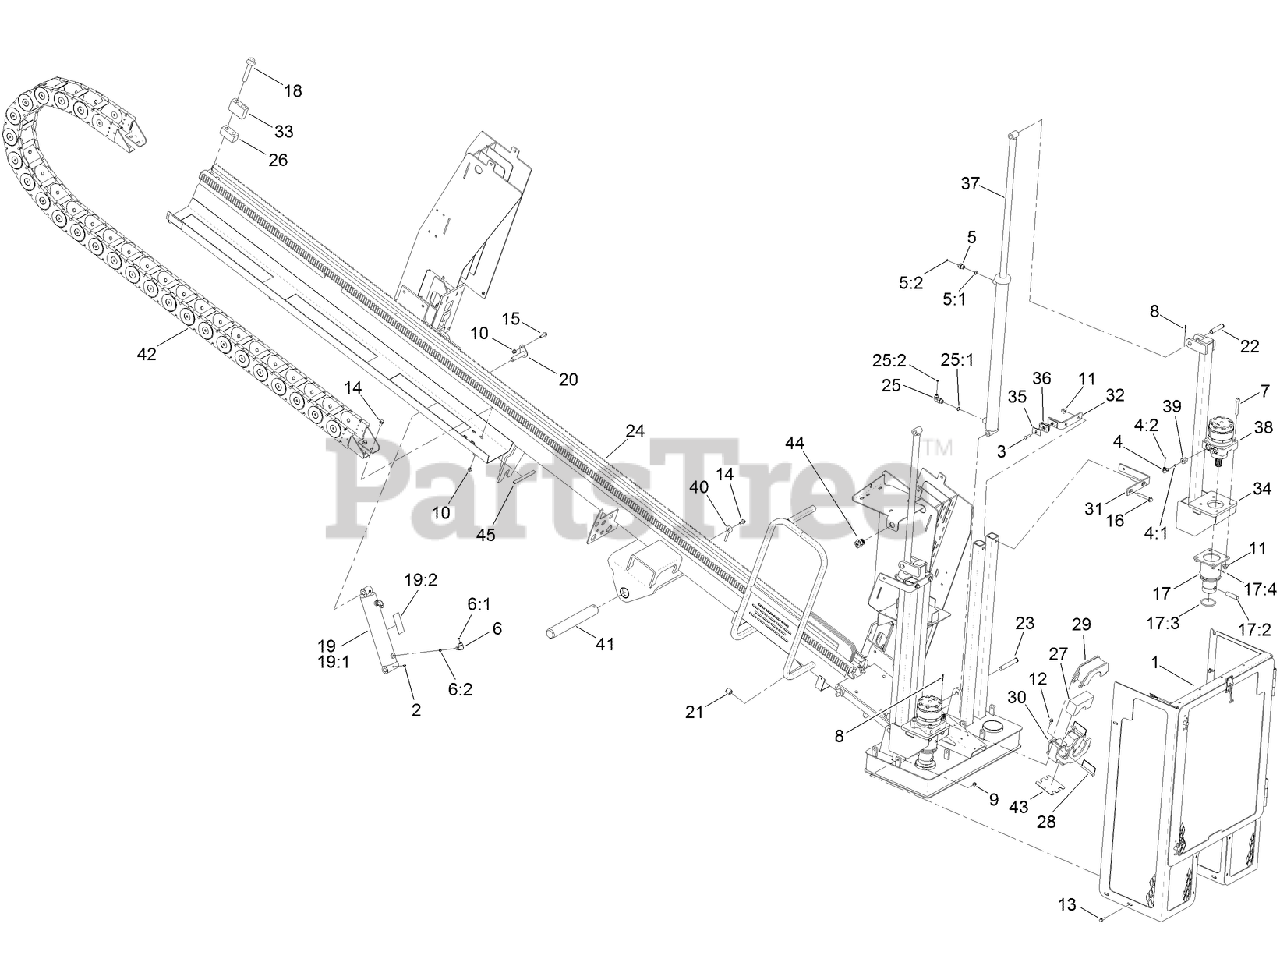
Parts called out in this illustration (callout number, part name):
1	STAKEDOWN CAGE ASM
2	FITTING-GREASE
3	SCREW-HH
4	FITTING-90 DEG
4:1	O-RING
4:2	O-RING
5	FITTING-STR
5:1	O-RING
5:2	O-RING
6	FITTING-ELBOW, 90 DEG
6:1	O-RING
6:2	O-RING
7	SCREW-HSH
8	PIN-COTTER
9	NUT-LOCK, HHF
10	NUT-LOCK, NI
11	NUT-LOCK, HHF
12	SCREW-HHF
13	SCREW-HHF
14	SCREW-HHF
15	SCREW-HHF
16	SCREW-HHF
17	STAKEDOWN COUPLER ASM
17:2	PIN-COUPLING, STAKE
17:3	O-RING
17:4	FITTING-GREASE
18	SCREW-HHF
19	LIFT CYLINDER ASM
19:1	CYLINDER-HYDRAULIC
19:2	DECAL-CAUTION, CYLINDER LOCK
20	PIN-FLAG
21	BUSHING-SPRING
22	PIN-CLEVIS
23	PIN-CLEVIS
24	THRUST FRAME ASM
25	FITTING-ELBOW 90
25:1	O-RING
25:2	O-RING
26	BLOCK-TAPPED
27	GUIDE-ROD, BUSHING
28	PIN-SELF LOCKING
29	GUIDE-ROD BUSHING, TOP
30	GUIDE-ROD BUSHING, BOTTOM
31	TIE-POST, STAKEDOWN
32	TIE-POST, HOSE BRACKET
33	STOP-CARRIAGE
34	STAKEDOWN
35	PLATE-COVER, TWIN
36	CLAMP-HALF (SET OF 2)
37	HYD CYLINDER ASM
38	HYD MOTOR ASM
39	REDUCER-STRAIGHT, THREADED
40	PIN-RETAINER
41	PIN-PIVOT, THRUST FRAME
42	CARRIER-HOSE
43	SHIM-ROD GUIDE, BOTTOM
44	RECEPTACLE-12V
45	TRIM-CARRIER, HOSE
